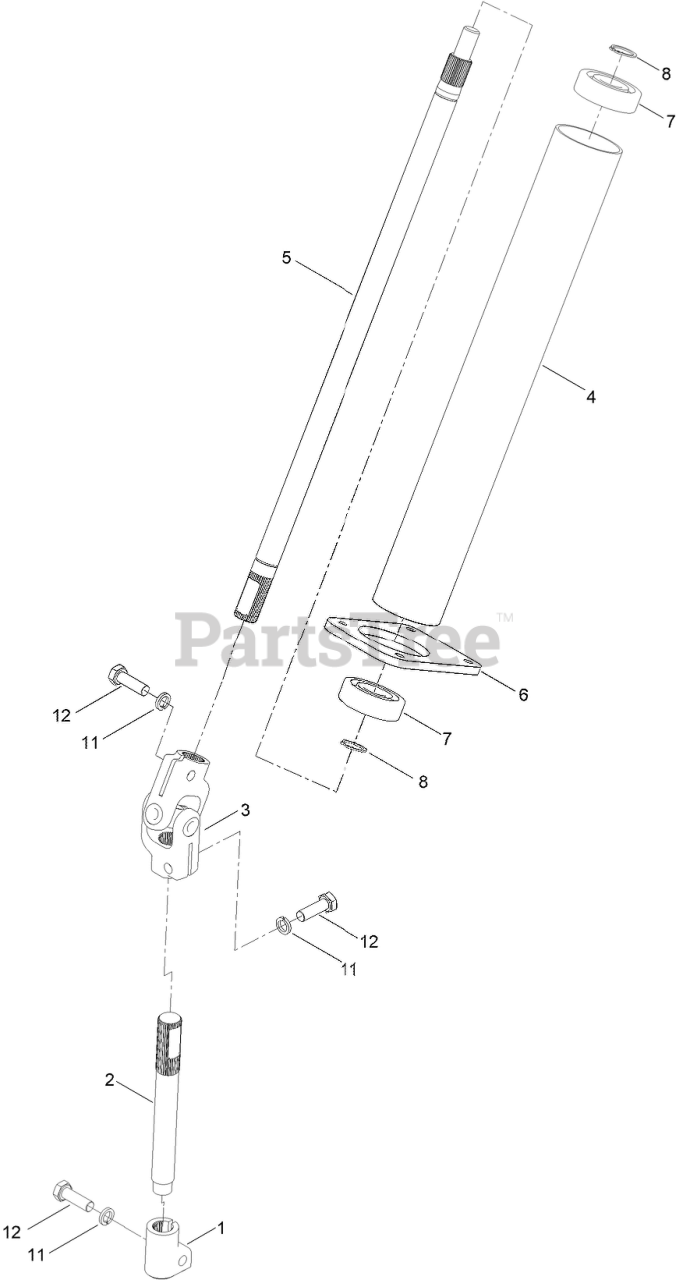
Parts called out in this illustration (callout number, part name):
1	CONNECTION, STEERING RACK
2	LOWER ROD, STEERING RACK
3	UNIVERSAL JOINT
4	COVER, UPPER STEERING ROD
5	UPPER ROD, STEERING
6	PLATE, MOUNTING STEERING ROD
7	BEARING, STEERING
8	CLIP, STEERING BEARING
11	WASHER, LOCK
12	BOLT, STEERING
